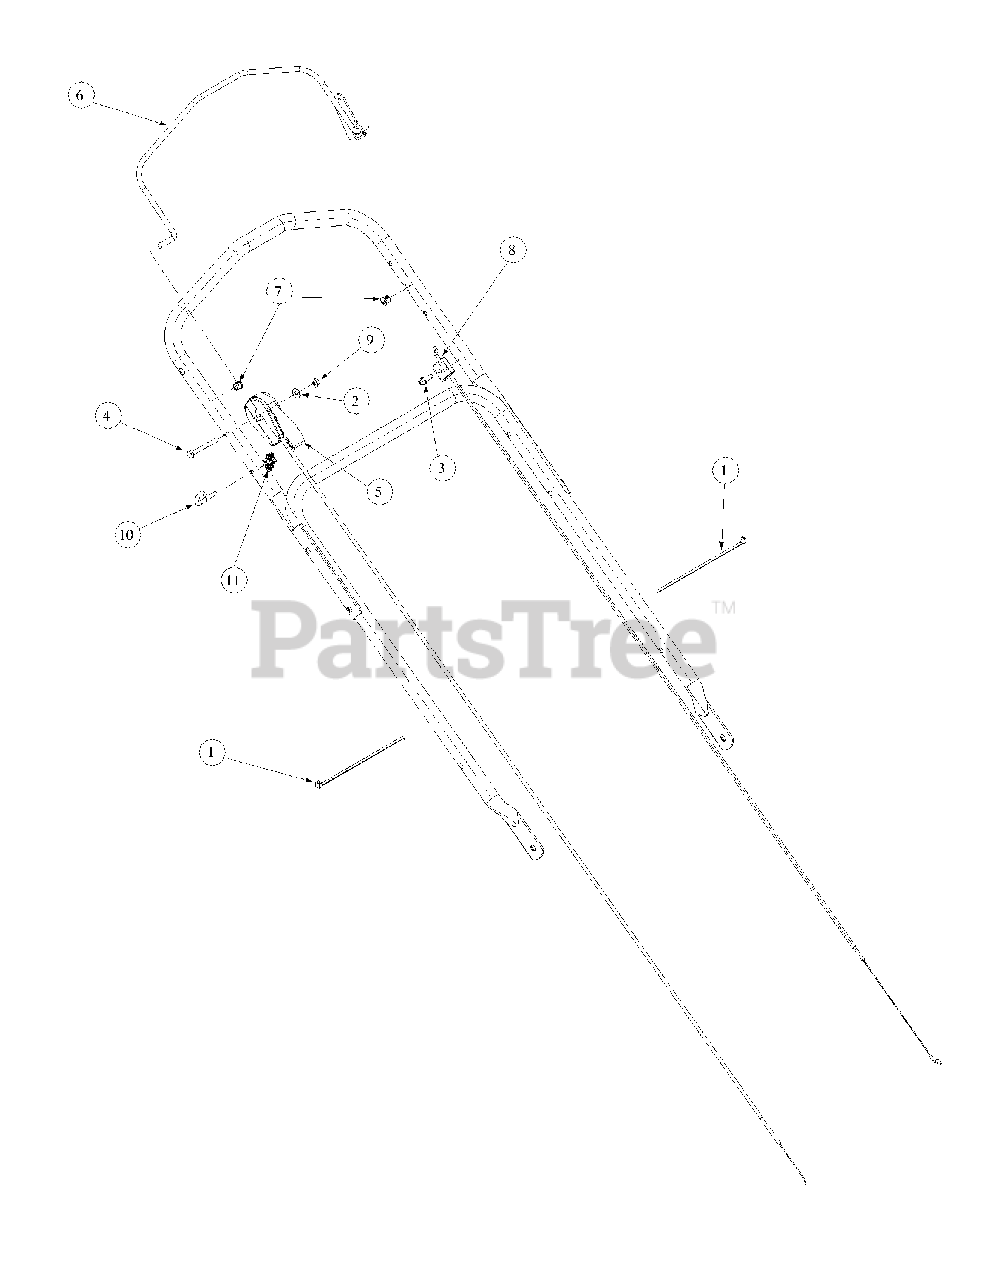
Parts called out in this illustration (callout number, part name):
1	Cable Tie, 3/16 X .05 X 7.4
2	Flatwasher 1/4 X .630 X .0515
3	Screw, TT, 1/4-20, 0.750, Hex Index Washer
4	HHCS, 1/4-20, 2.25, GR5, Standard
5	Control Throttle, W/Cable, KAW
6	Control Lever, W/0 BBC
7	Bushing, .3125 Diameter, Snap
8	Control Cable
9	Nut, 1/4-20, Hex Flange, Lock, Group F
10	Eye Bolt, 1/4-20, Bent Rope GDE
11	Handle Knob, ERS 1/4-20
